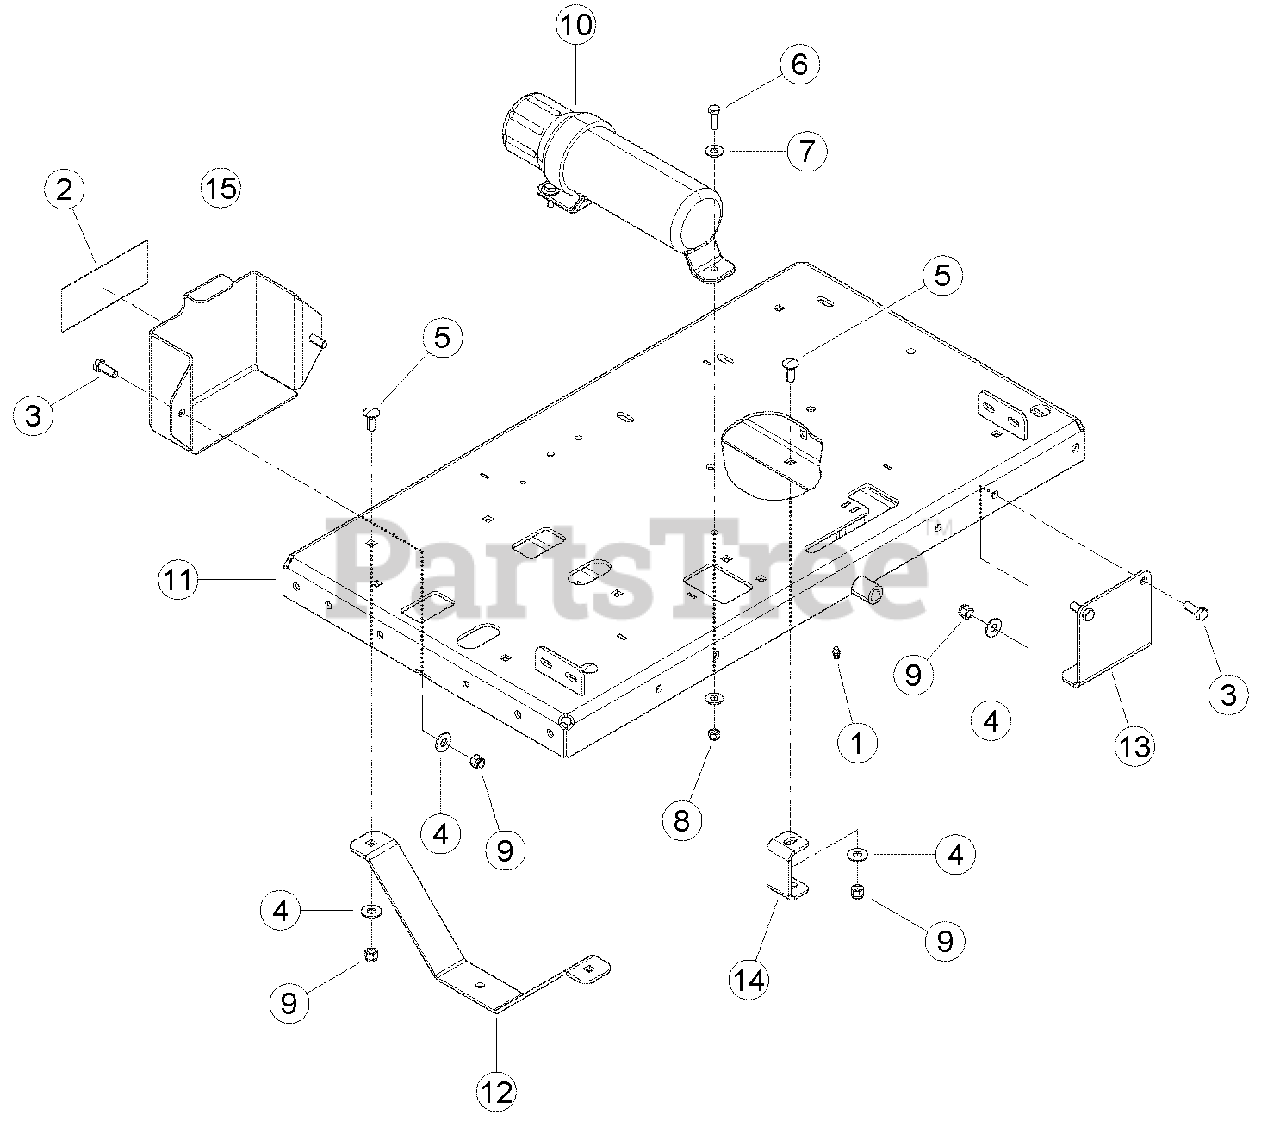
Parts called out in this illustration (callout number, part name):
1	FITTING, 1/4 SELF-TAP GREASE
2	DECAL, MUTILINGUAL MANUAL
3	BOLT, 3/8 X 1 HEX HD GR5 ZP
4	WASHER, 3/8 FLAT ZP
5	BOLT, 3/8 X 1 CRG GR5 NC ZP
6	BOLT, 5/16 X 1 HEX HD GR5 NC ZP
7	WASHER, 5/16 FLAT ZP
8	NUT, 5/16 NE NYLOCK ZP
9	NUT, 3/8 NE NYLOCK ZP
10	CONTAINER, MANUAL
11	WELDMENT, CHIPPER TRAILER
12	PLATE, HITCH
13	BRACKET, L + G AXLE
14	BRACE, L + G AXLE
15	BOX, WP18-12 BATTERY
16	POLE, L & G HITCH
17	PLATE, HITCH POLE
18	AXLE, L & G
19	BRACKET, L & G AXLE
20	BRACE, L & G AXLE
21	STAND, JACK
